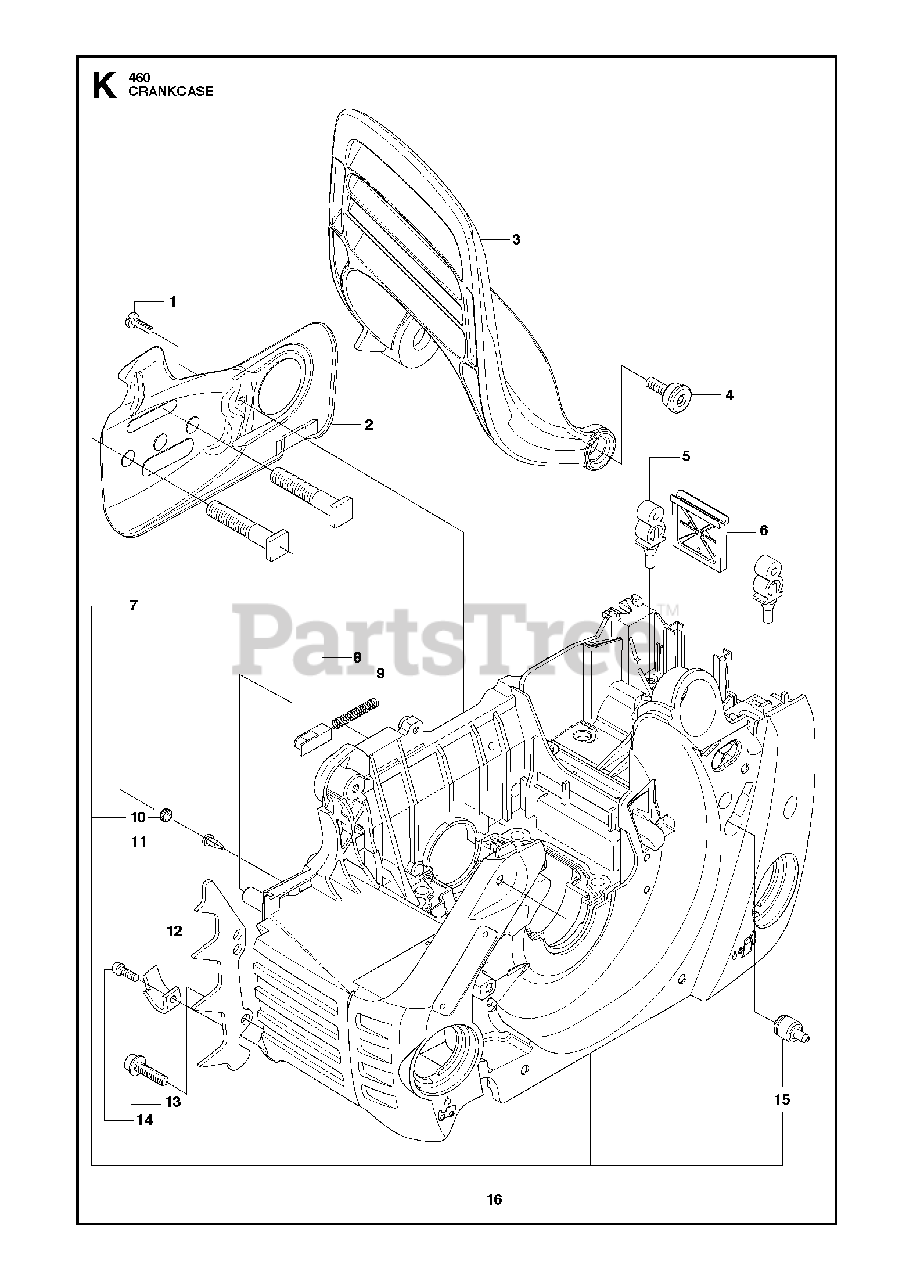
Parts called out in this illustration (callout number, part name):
3	HAND GUARD
4	SCREW, HAND GUARD
7	BOLT
9	LOCK SPRING
10	PLUG
11	VALVE-CHECK (DUCKBILL)
12	FELLING DOG
13	SCREW IHSCFT
14	CHAIN CATCHER
15	FUEL TANK VENT
16	CRANKCASE
